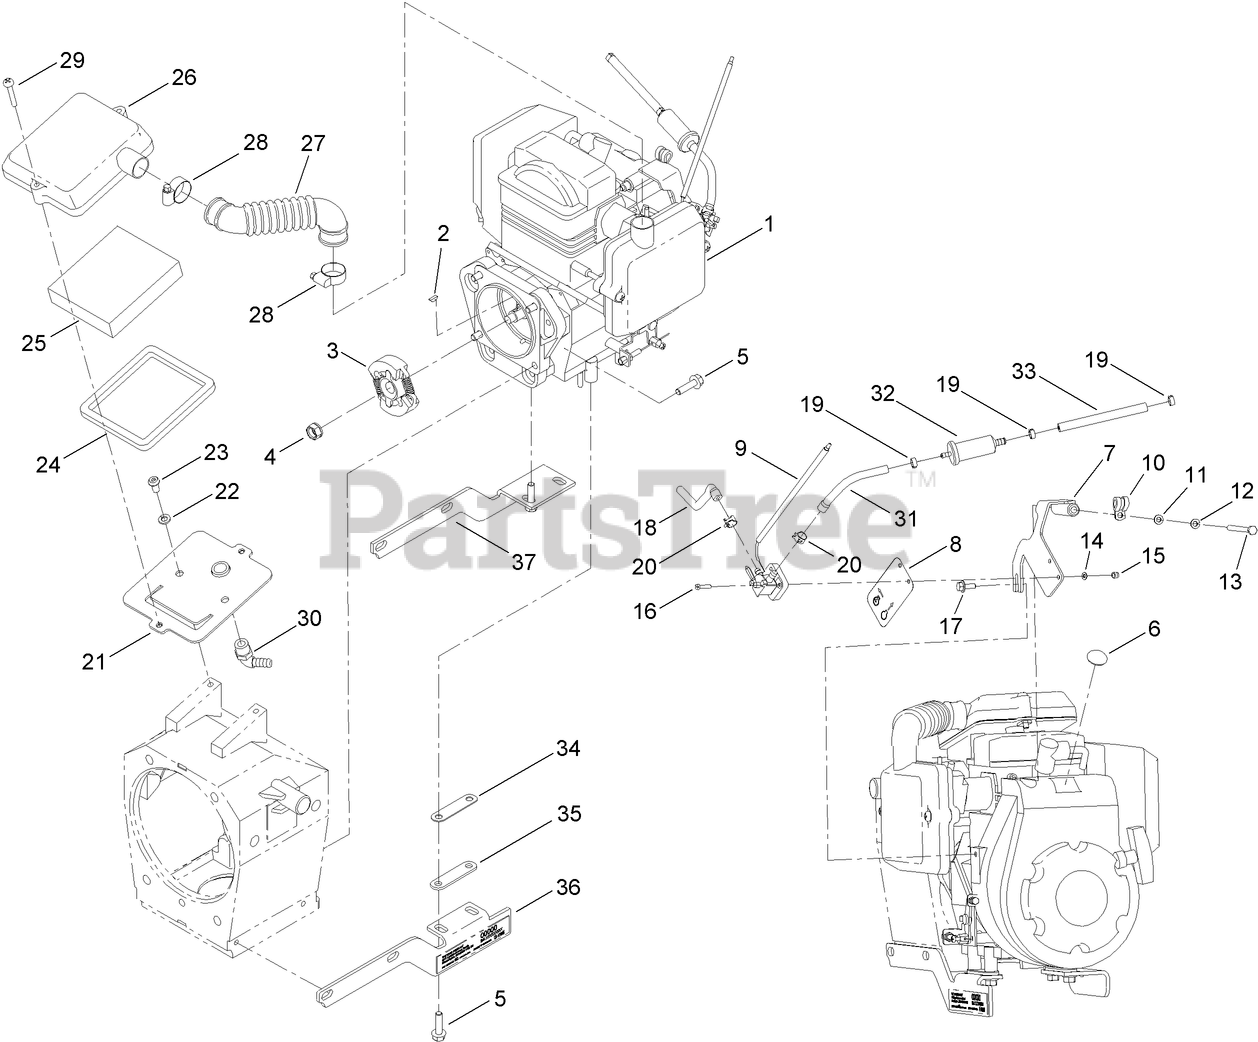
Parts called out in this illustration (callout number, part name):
1	ENGINE-HONDA, GX100
2	KEY-WOODRUFF
3	CLUTCH-FRICTION
4	NUT-HEX FLANGE
5	SCREW-HHF
6	PLUG-RUBBER
7	BRACKET-VALVE, FUEL
8	HANG TAG-RUN, STOP
9	FUEL SHUT OFF VALVE ASM
10	CLAMP
11	WASHER-FLAT
12	WASHER-LOCK, SPRING
13	SCREW-HH
14	WASHER-FLAT
15	NUT-LOCK
16	SCREW-HH
17	SCREW-HH
18	HOSE-FUEL
19	CLAMP-HOSE, FUEL
20	CLAMP-HOSE
21	BASE-PREFILTER
22	WASHER-LOCK
23	SCREW-HSBH
24	GASKET-PREFILTER
25	FILTER-AIR, PREFILTER
26	COVER-AIR FILTER
27	TUBE-AIR
28	CLAMP-WORM
29	SCREW-PPH
30	FITTING-90 DEG
31	HOSE-FUEL
32	FILTER-DIAPHRAM, FUEL
33	HOSE-FUEL
34	SHIM-ENGINE (16GA)
35	SHIM-ENGINE (11GA)
36	BRACKET-SUPPORT, LH
37	BRACKET-SUPPORT, RH
